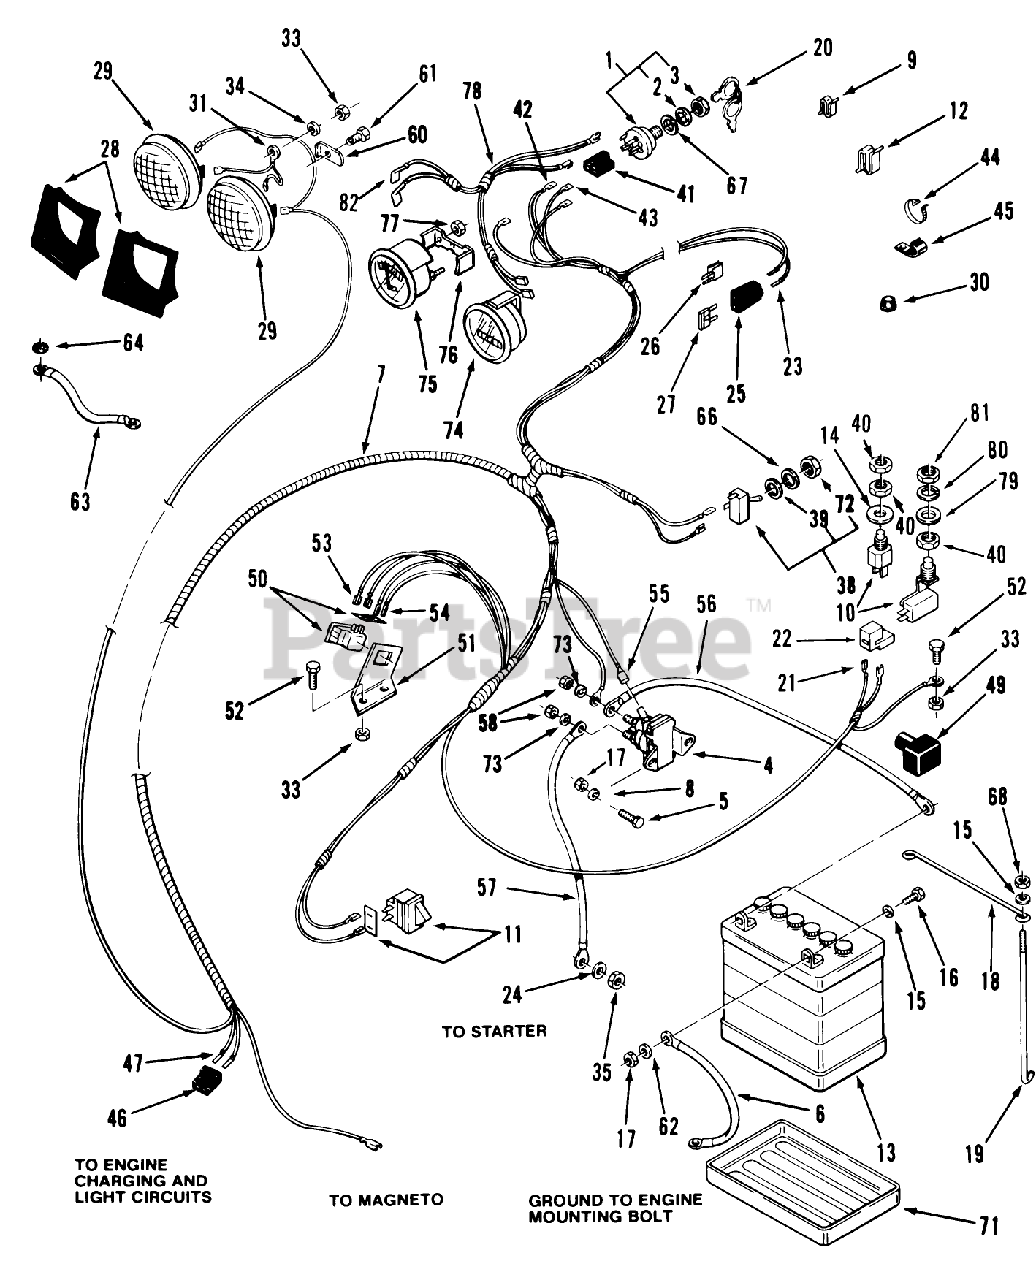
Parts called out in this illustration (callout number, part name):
4	SOLENOID-STARTER
6	WIRE -BLACK
10	SWITCH-BALL
12	CLIP-CABLE
14	WASHER-FLAT
18	ROD-HOLD DOWN
22	CONNECTOR BODY
23	TERMINAL FUSE
27	FUSE-BLADE, 15 AMP
29	HEADLAMP
38	SWITCH-LIGHTS
39	TAB-WASHER
42	TERMINAL-TAB RCPT
45	CLIP
46	Conn Body Part of 7
50	SEE WH SB 442
53	Terminal
54	Wire Terminal (Part of 1)
55	Terminal-Part of 5
56	WIRE - 14" BLACK
57	ASSY WIRE
60	LOCK-HEADLIGHT
61	Bolt
63	WIRE GROUND
66	Washer
71	TRAY BATTERY
76	CLAMP MOUNTING
77	HEX NUT 10-32 E.S. + + USE 3296-21 + +
81	NUT HEX SPECIAL
82	VALVE LEVER GRIP
